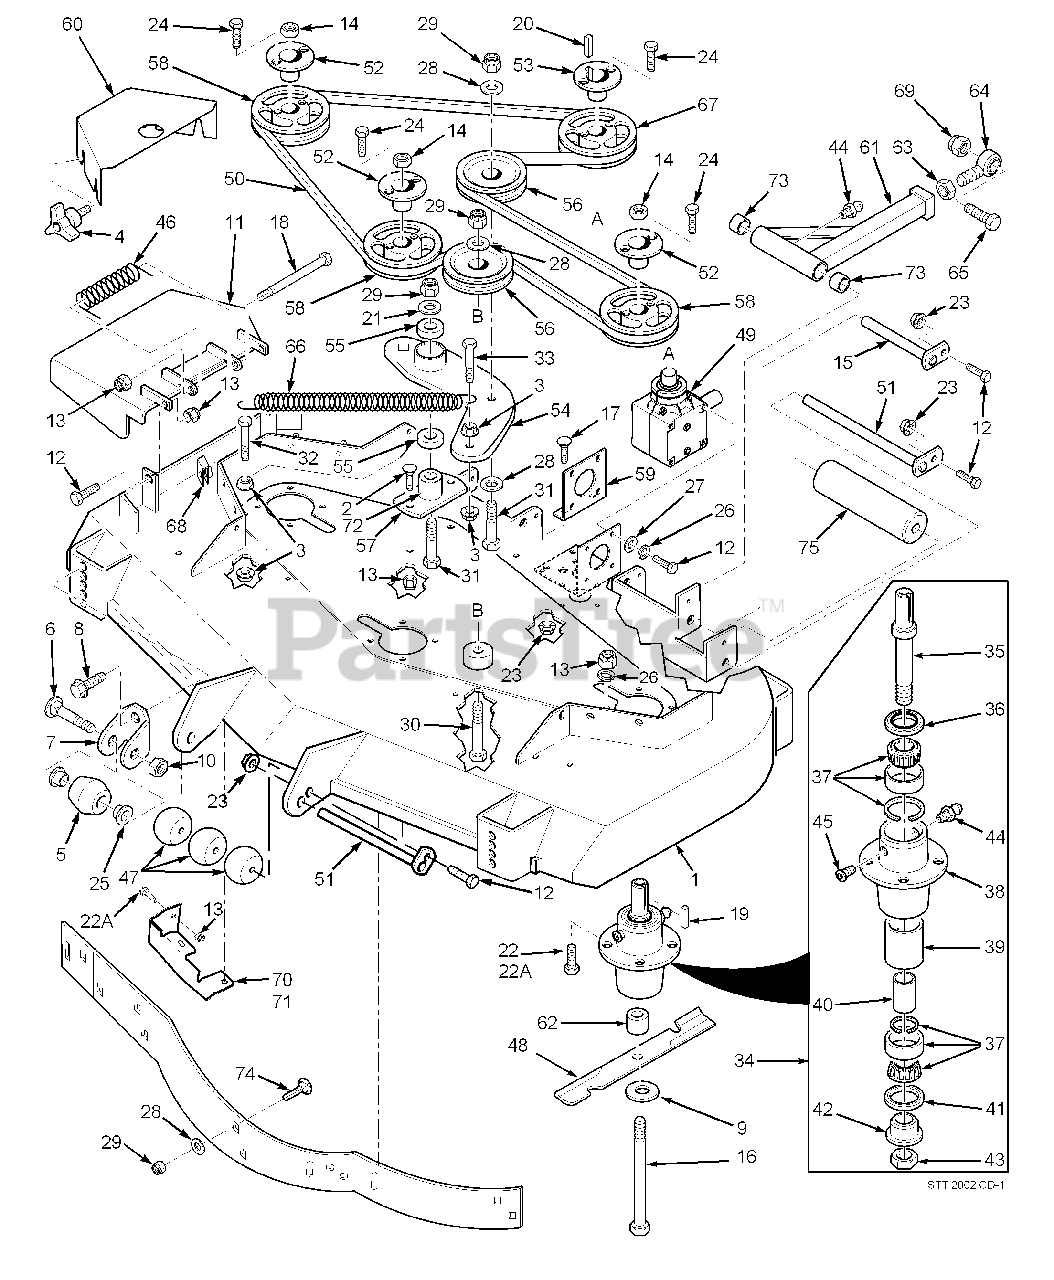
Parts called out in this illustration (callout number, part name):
1	Cutter Deck Advantage
2	Bolt, Carriage 5/16-18 x 1"
3	Nut , Hex Serrated Flange 3/8-16
4	Wing nut, 3/8-16
5	Anti-Scalp Wheel
6	Bolt, Carriage 3/8-16 x 4"
7	Anti-Scalp Wheel Bracket
8	Bolt, Hex Serrated Flange 3/8-16 x 1"
9	Flatwasher, 5/8"
10	Locknut, 3/8-16 Center Lock
11	Discharge Chute Advantage - Large
12	Bolt, Hex Head 5/16-18 x 1-3/4" - Front
13	Nut, Hex Elastic Stop 5/16-18
14	Nut, 5/8-11 UNC
15	Push Arm Shaft
16	Bolt, Hex Head 5/8-11 x 9-1/2"
17	Bolt, Carriage 5/16-18 x 3/4"
18	Bolt, Hex Head 5/16-18 x 4-1/2"
19	Key, 1/4 x 1/4 x 2"
20	Key, 1/4 x 1/4 x 1-1/4"
21	Flatwasher,3/8-.39 x .938 x .105 HD
22	Bolt, Hex Head 5/16-18 x 1-1/4"
22A	Bolt, Hex Head 5/16-18 x 1-1/2"
23	Nut, Hex Serrated Flange 5/16-18
24	Bolt, Hex Head 1/2-20 x 3/4"
25	Bushing, .376 I.D. Oilite
26	Lockwasher, 5/16"
27	Flatwasher, 5/16"
28	Flatwasher, 3/8"
29	Nut, Hex Elastic Stop 3/8-16
30	Bolt, Hex Head 3/8-16 x 3-1/4"
31	Bolt, Hex Head 3/8-16 x 2-1/2"
32	Bolt, Hex Head 3/8-16 x 1-1/2"
33	Bolt, Hex Head 3/8-16 x 1-1/2" Grade 8
34	Spindle Assembly
35	Spindle Shaft
36	Seal, Top
37	Bearing Assembly
38	Spindle Housing
39	Spacer, Outside
40	Spacer, Inside
41	Seal, Bottom
42	Spindle Bushing, Bottom
43	Nut, Special 1 - 1/16-18
44	Grease Fitting
45	Relief Fitting, Tapered Spindle
46	Spring, Discharge Chute
47	Wheel, Anti-Scalp
48	Cutter Blade, 21"
49	Gearbox Assembly, Deck Drive
50	Belt, Cutter Deck Drive
51	Roller Shaft
52	Tapered Hub, 1-1/8" Bore
53	Tapered Hub, 1" Bore
54	Idler Arm, Cutter Deck
55	Bearings, Ball
56	Pulley, Idler
57	Base, Idler Pivot
58	Pulley, 6.75 O.D.
59	Mounting Plate, Gearbox
60	Belt, Cover
61	Pusharm
62	Spacer, Spindle Bottom
63	Nut, Hex Head 5/8-18 UNF
64	Rod End, 5/8" Male RH Thread
65	Bolt, Hex Head 5/8-11 x 4-1/2"
66	Spring, Cutter Deck
67	Pulley, 6.35 O.D.
68	U-Nut, 3/8-16
69	Nut, Hex Elastic Stop 5/8-11
71	Discharge Baffle 61"
72	Pivot, Idler - Short
73	Bushing
74	Bolt, Carriage 3/8-16 x 1"
75	Guide, Roller
